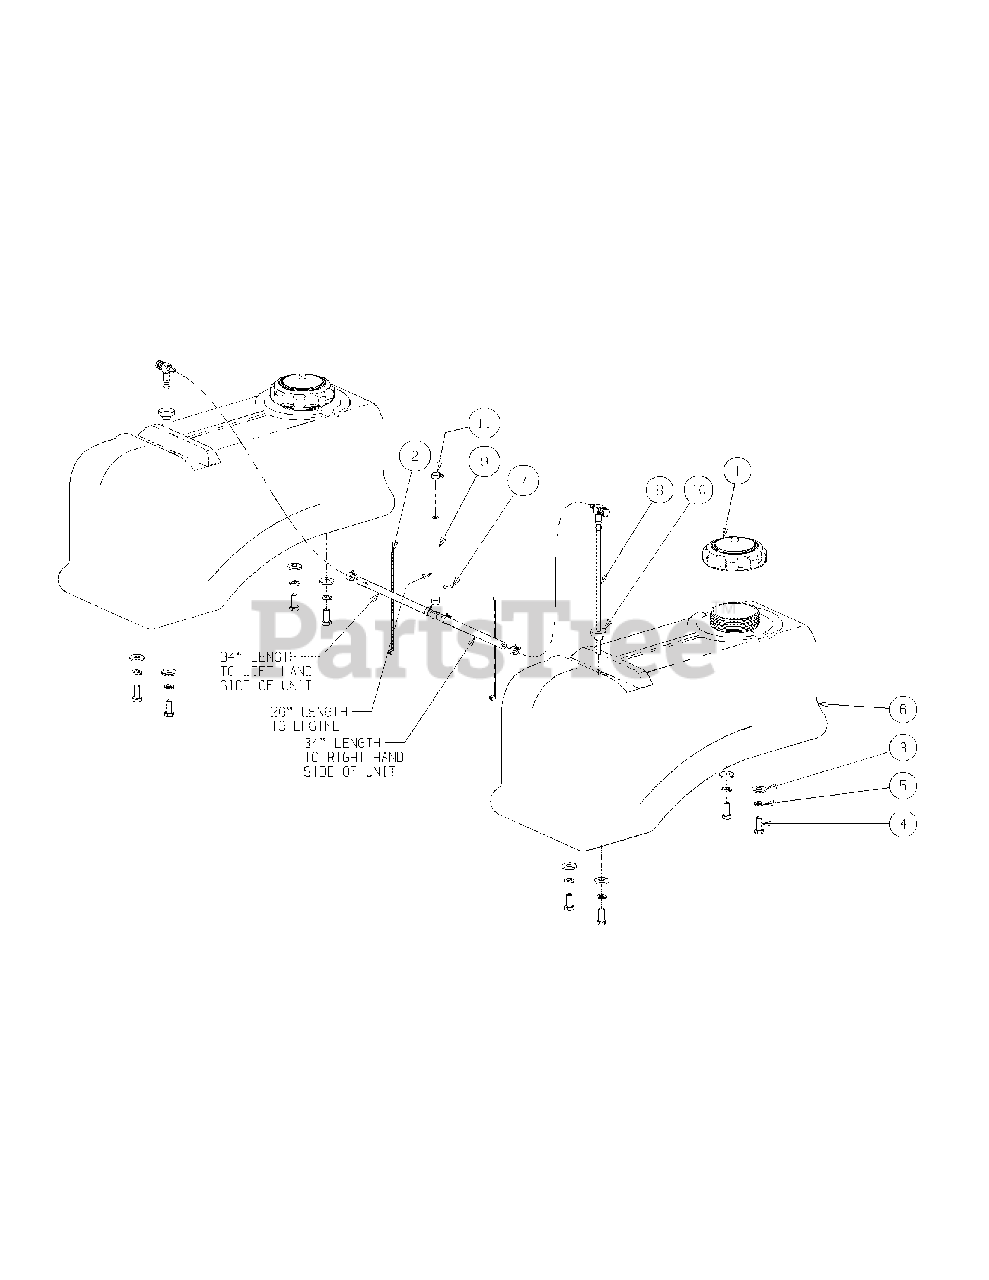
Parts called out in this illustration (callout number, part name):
1	Fuel Cap, 3.5, Tethered
2	Cable Tie
3	Flat Washer, .406 ID, 1.0 OD, .105
4	Hex, Cap Screw, 3/8-16, .88
5	Lock Washer, 3/8
6	Fuel Tank
7	Flat Washer, 1.4 x .630 x .0515
8	Fuel Fitting
9	Fuel Hose Assembly includes:
9	Hose, 1/4" Fuel Line
9	Clamp, Union
9	Tee Fitting, Fuel
10	Grommet, Fuel Tank
11	Hose Clamp, SAE #4: 1/4-5/8, SS
